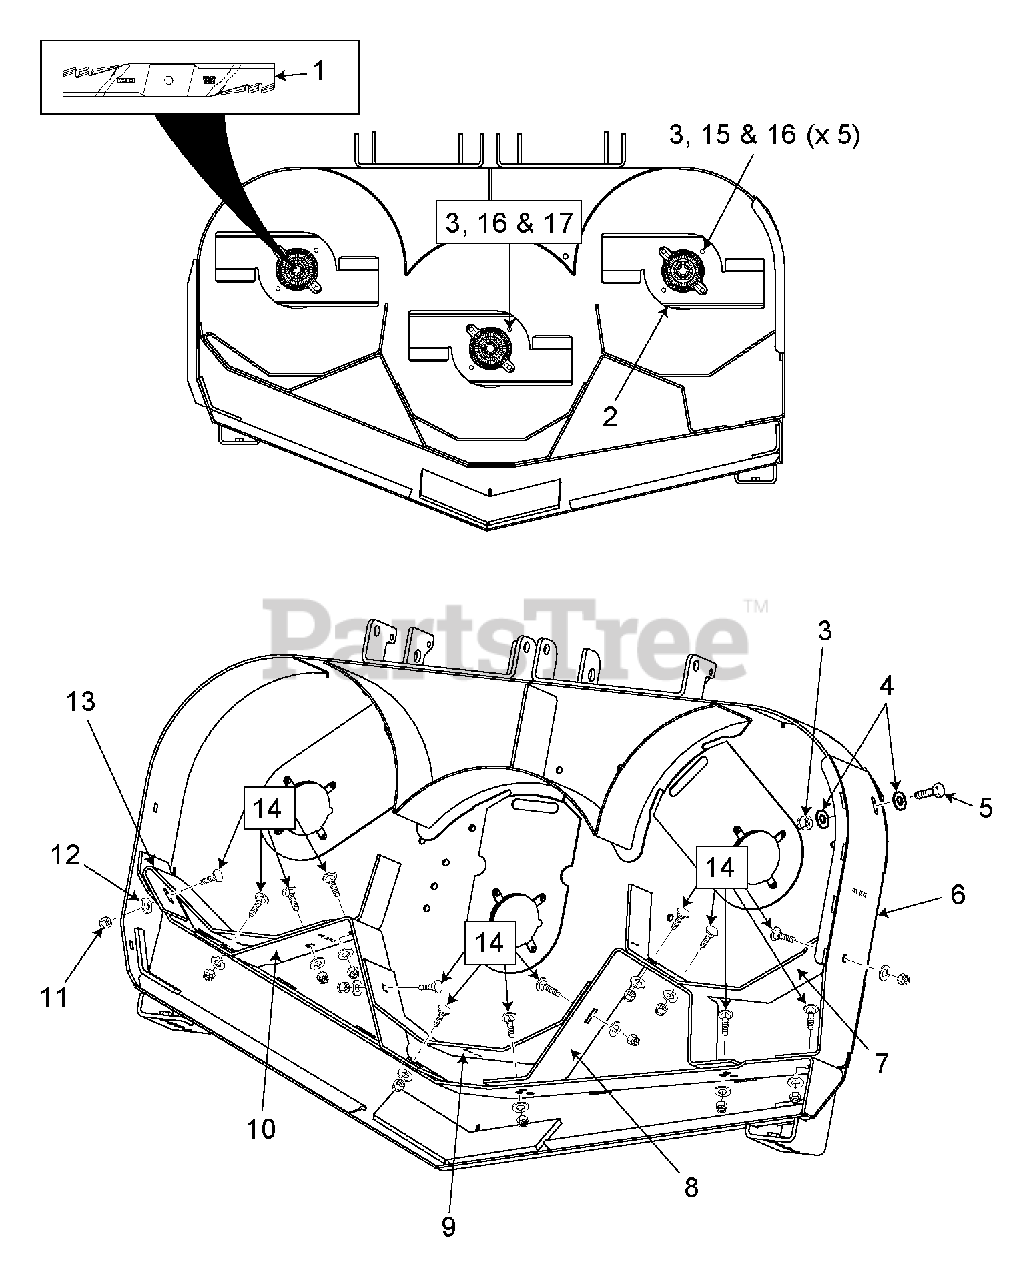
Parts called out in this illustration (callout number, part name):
1	Eliminator Mulch Blades
2	Hurricane Plate, 48
3	Elastic Stop Nut 5/16-18
4	Flatwasher 5/16"
5	H.H. Bolt 5/16-18 x 1"
6	Mulch Plate
7	R.H. Baffle, Mulch Divider
8	R.H. Mulch Baffle
9	Center Mulch Baffle
10	L.H. Mulch Baffle
11	Elastic Stop Nut 3/8-16
12	Flatwasher 3/8"
13	L.H. Baffle, Mulch Divider
14	Carriage Bolt 3/8-16 x 1"
15	H.H. Bolt 5/16-18 x 1-3/4"
16	Lockwasher 5/16"
17	H.H. Bolt 5/16-18 x 2"
